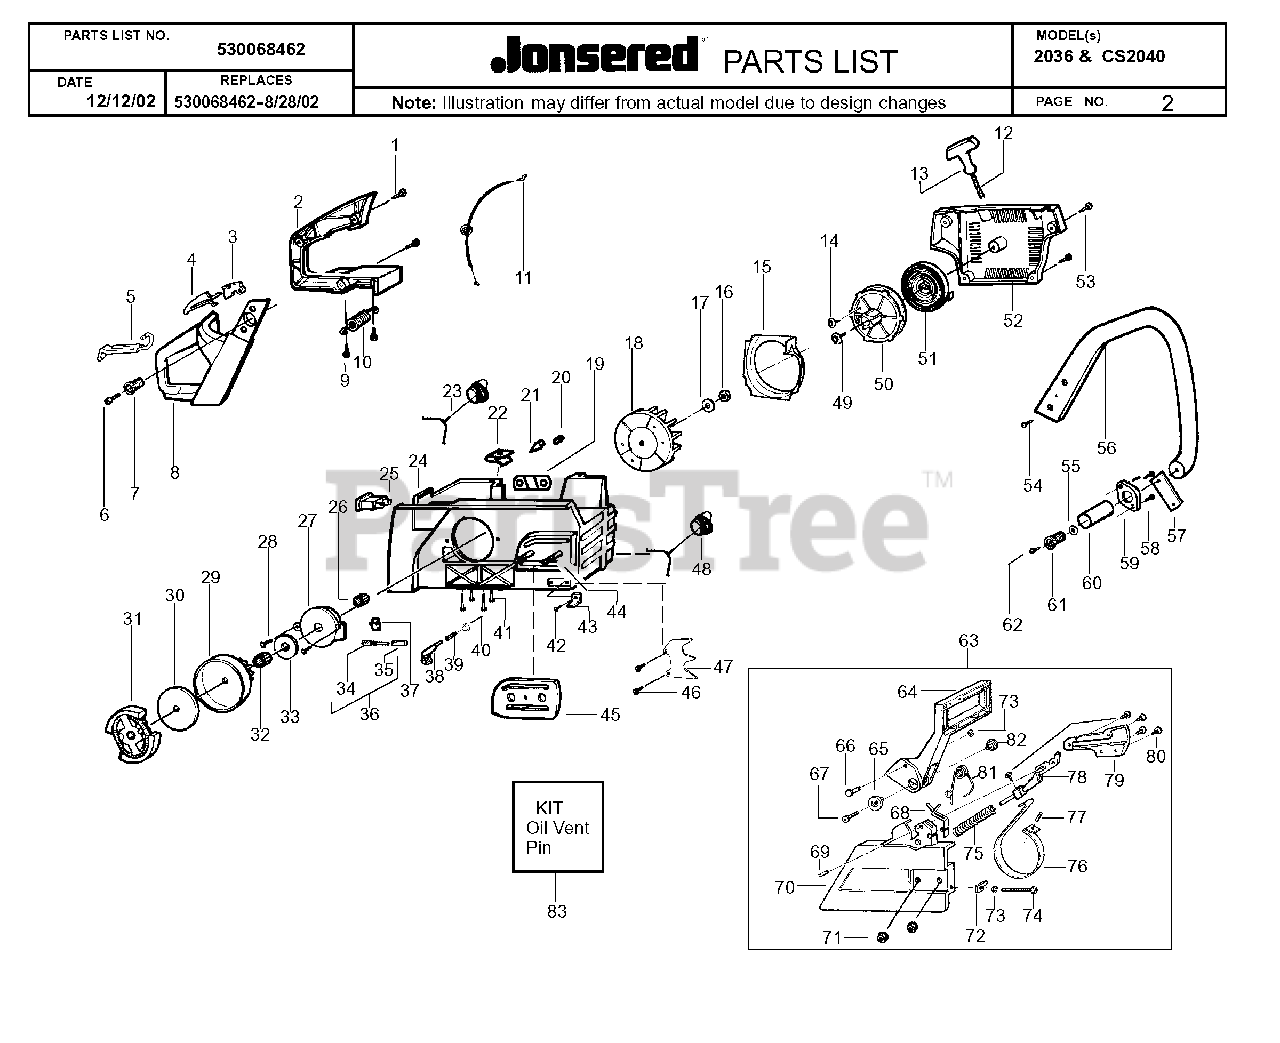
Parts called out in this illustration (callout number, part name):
2	HANDLE
3	THROTTLE TRIGGER
4	THROTTLE LOCK
5	CHOKE LEVER
8	HANDLE
9	SCREW,FRONT HBAR 36/41
11	THROTTLE WIRE
15	AIR CONDUCTOR
16	NUT-FLYWHEEL
17	WASHER-FLYWHEEL
18	ROTOR COMPL. 36/41
19	PLATE,BAR MOUNT
20	VENT,FUEL TANK 36/41
21	VALVE-CHECK (DUCKBILL)
23	FUEL CAP CPL
26	OILER GEAR 36/41
27	OIL PUMP HOUSING
30	FRICTION DISC,CLUTCH 36/41
31	CLUTCH ASSEMBLY
32	NEEDLE BEARINGS 36/41
33	DUST COVER 36/41
34	PLUNGER & GEAR ASSEMBLY
35	OIL PUMP BARREL
36	OILER ASS'Y 36/41
37	PRESSURE SEAL,OILER 36/41
38	OIL PICK-UP
39	FILTER
40	PLUG
41	SCREW M5-0.8X35M TAP
43	CHAIN CATCHER 36/41
44	BAR BOLT 36/41
45	BAR PLATE
46	SCREW-10-16 X 1/2, TYPE 2
47	SPIKE 36/41
48	OIL TANK CAP
50	PULLEY 36/41
51	RETURN SPRING
52	STARTER DEVICE
53	SCREW,STRTR CVR 36/41
56	%HANDLE
58	SCREW 8-16 X 9/16 (PLAS
63	CHAIN BRAKE JONS RED
64	HANDGUARD
65	JOURNAL, RIGHT
66	PIVOT PIN
68	SPRING-POSITION
70	COVER
72	ADJUST PIN,BAR 36/41
75	%COMPRESSION SPRING
76	BRAKE BAND
78	KNEE LINK
80	SCREW
82	SHAFT PIVOT
530047061	CLUTCH DRUM ASSY
530069342	SPUR SPRKT .325 7T 36/41
